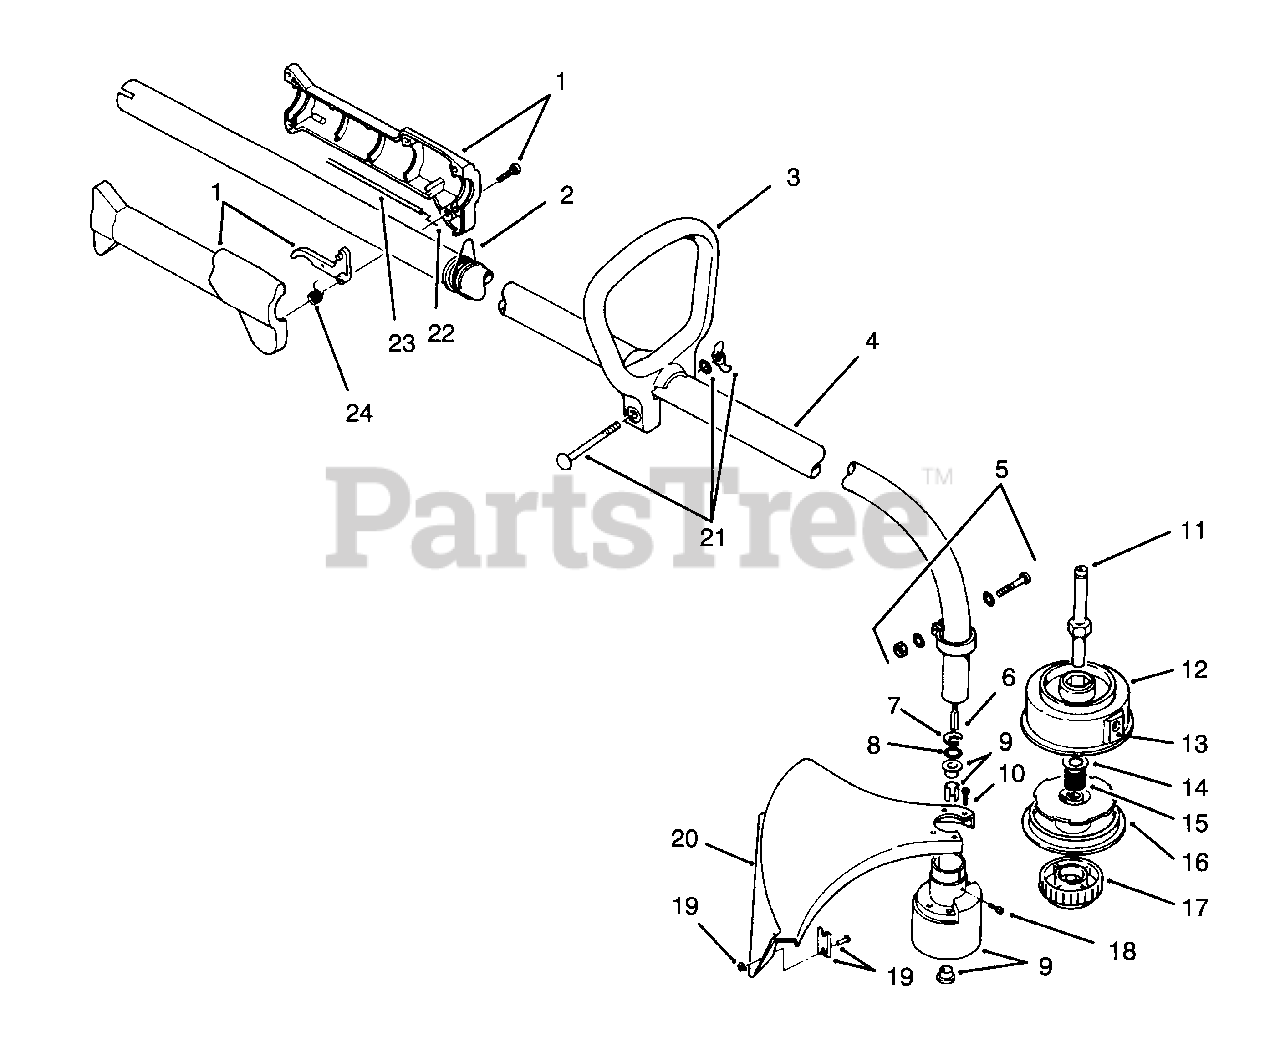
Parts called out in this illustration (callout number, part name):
1	Assy.-Throttle & Trigger (Incl. 6 Screws)
2	Clip-Shoulder Strap
3	D-Handle
4	Assy.-Drive Shaft Housing
5	Assembly-LowerClamp
6	Shaft-Flexible Drive
7	Ring-Retaining
9	Assy.-Bushing Housing
10	Assy.-Guard Mount Screw
11	Shaft-Spool
12	Assy. Outer Spool & Eyelet
14	Retainer
16	Reel-Inner
17	Assembly-Bump Head
18	Screw-Anti-Rotation
19	Assembly-Blade (Incl. 2 screws & 2 Nuts)
20	Assembly-Guard & Blade (Incl. Ref. No. 19)
21	HardwareAssy., D-Handle
22	Cable-Throttle
23	Assy.-Throttle Cable
24	Spring-Throttle Trigger
